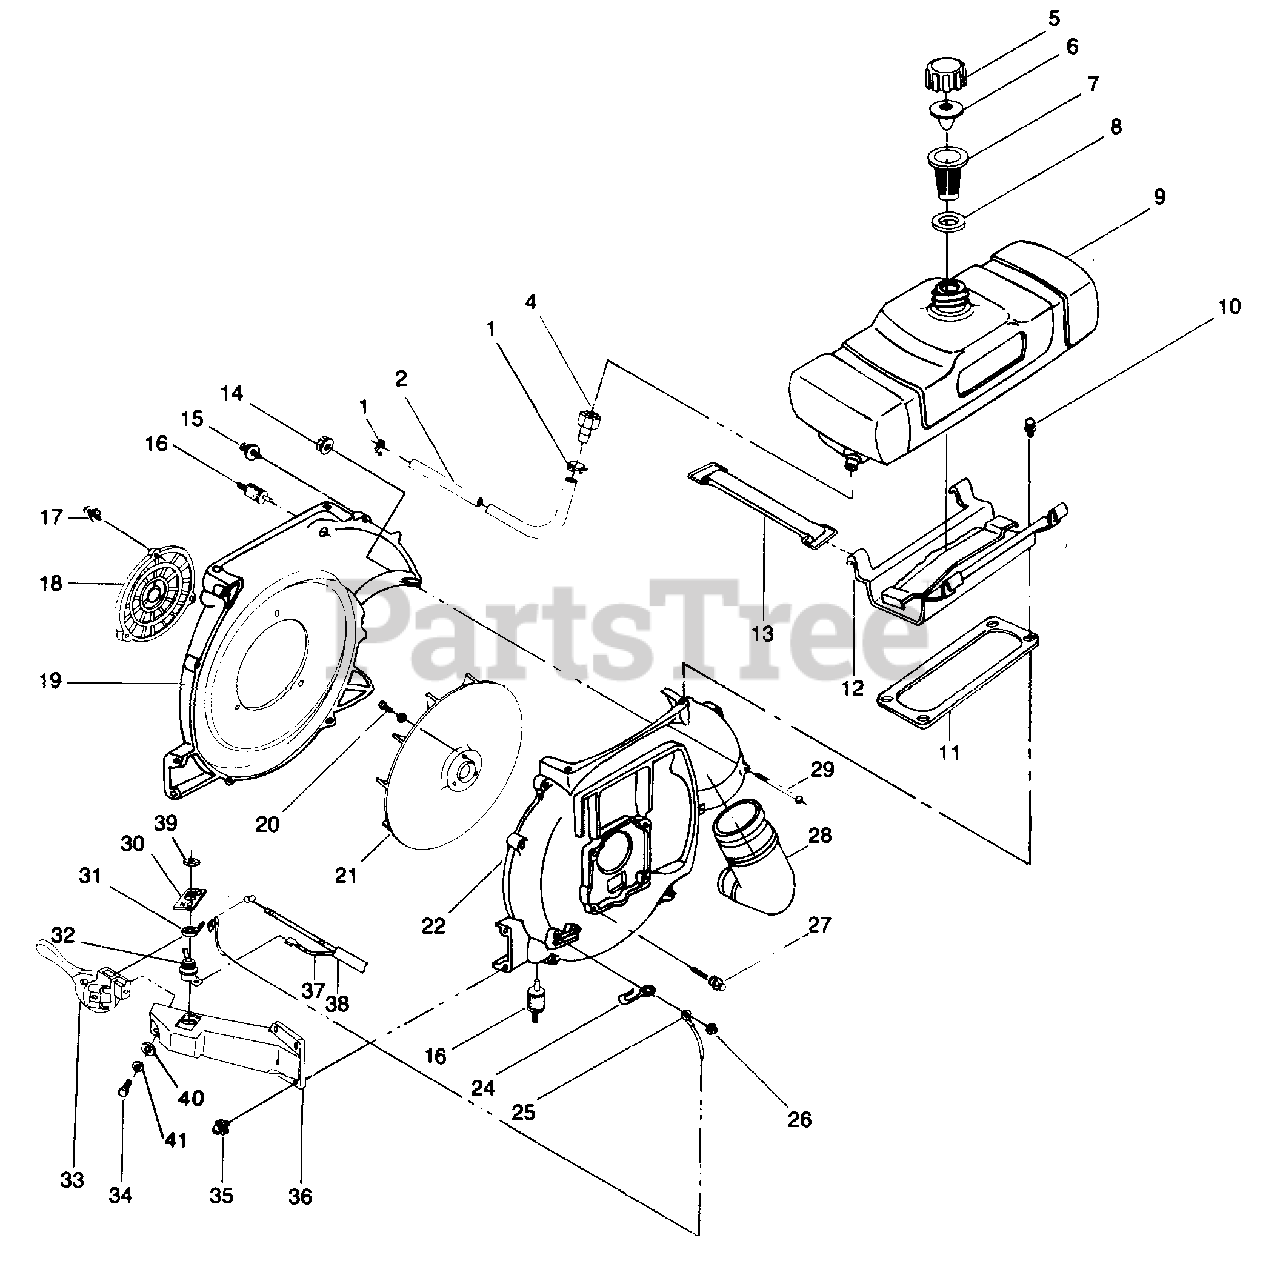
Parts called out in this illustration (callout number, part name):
1	Clamp - Fuel Housing (obsolete)
2	Fuel Hose
4	Union Assembly
5	Cap - Fuel
6	Breather
7	Strainer
8	Washer - Rubber
9	Fuel Tank
10	Bolt (6 x 12mm) - Hex
12	Tank Base
13	Tank Strap - Rubber
14	Flange Nut (5mm)
15	Bolt (6 x 25mm) - Hex
16	Isolator
17	Screw (6 x 14mm)
18	Fan Cover
19	Fan Case - Front
20	Bolt (6 x 25mm) - Hex
22	Fan Case - Rear
24	Clip - Fuel Hose
25	Grounding Wire
26	Screw (6 x 12mm)
27	Bolt (6 x 45mm) - Hex
29	Screw (5 x 55mm)
30	Switch Plate
31	Grounding Connector
32	Grounding Switch
33	Throttle Lever
34	Bolt (6 x 10mm) - Hex
35	Screw (5 x 16mm)
36	Control Arm
37	Electrical Wire
38	Tube - Throttle Wire
39	Nut - Hex - 11mm
40	Washer - Flat - 6mm (outside vendor)
41	Lockwasher - 6mm
